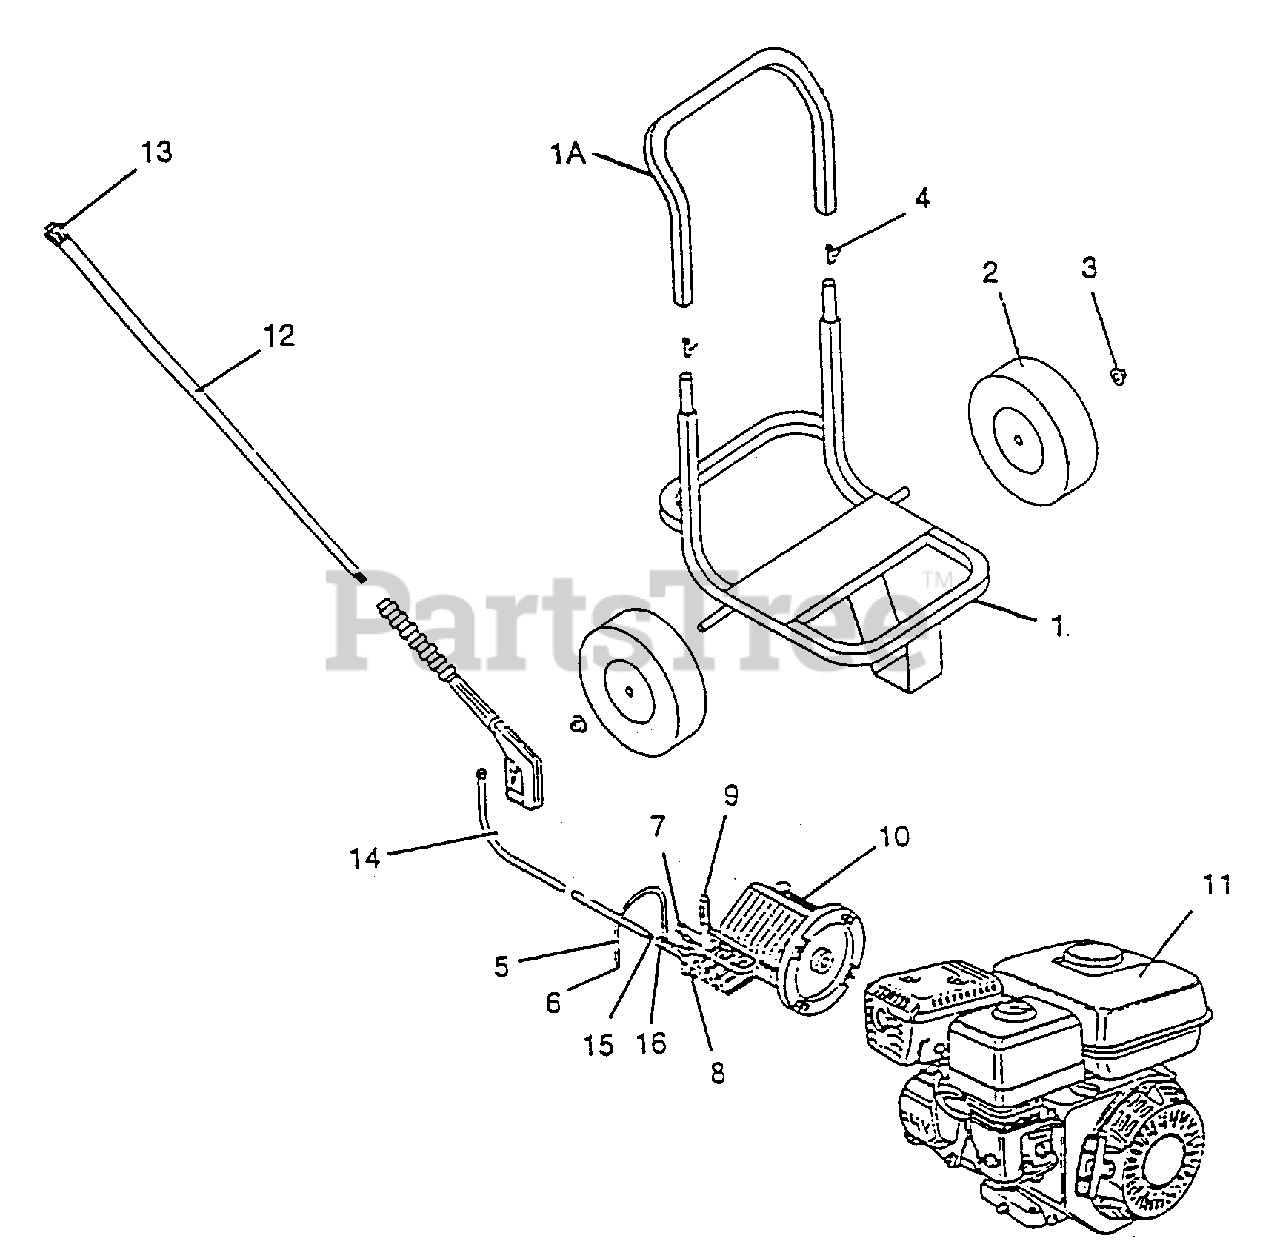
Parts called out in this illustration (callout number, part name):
1A	Handle Bar
2	Semi Pneumatic Wheels
3	Hub Caps
4	Valco Spring Buttons
5	Nylon Braid Hose with Screen
6	Hose Screen
7	Garden Hose Adapter
8	Thermal Relief Valve
9	Unloader Valve
11	11 HP Honda with Pull Start
12	Hi/Low Nozzle/Wand
14	Hose R1-3/8" x 50'
15	3/8" Female Q.C. Plug
16	Female Q.C. Socket
